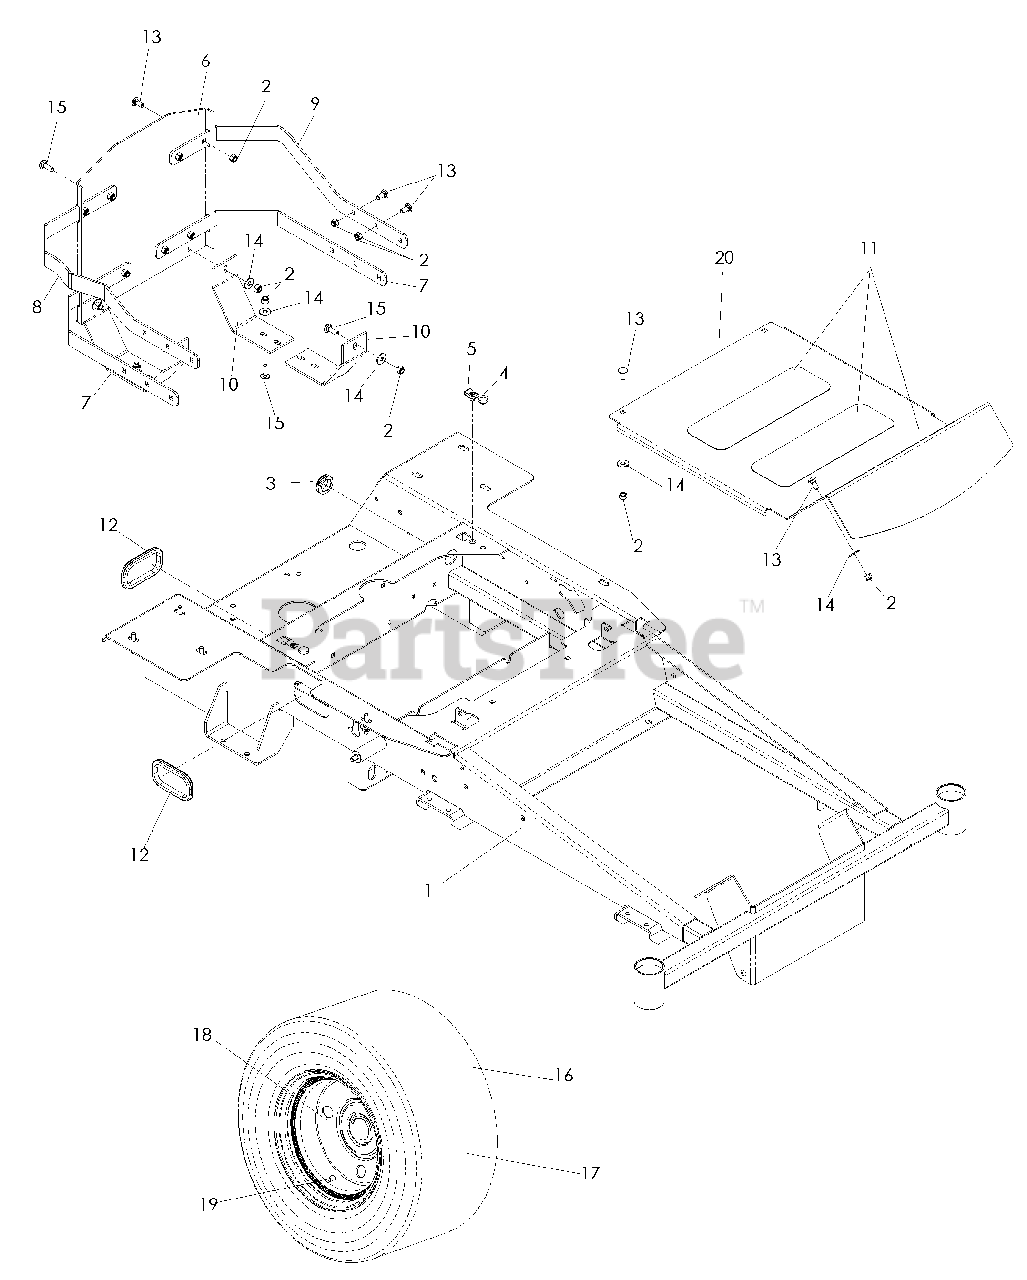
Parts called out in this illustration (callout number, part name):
1	MAIN FRAME W/DECALS
2	NUT 5/16-18 NYLOC
3	RUBBER GROMMET
4	GROMMET, BUMPER
5	NUT 5/16-18 RETAINER
6	ENGINE GUARD
7	LOWER GUARD
8	UPPER RT HAND GUARD
9	UPPER LT HAND GUARD
10	SKID PLATE
11	PAD, ABRASIVE
13	RHSNB 5/16-18 x 3/4
14	WASHER 5/16
15	RHSNB 5/16-18 x 1
16	TIRE & RIM
18	RIM
19	VALVE STEM
